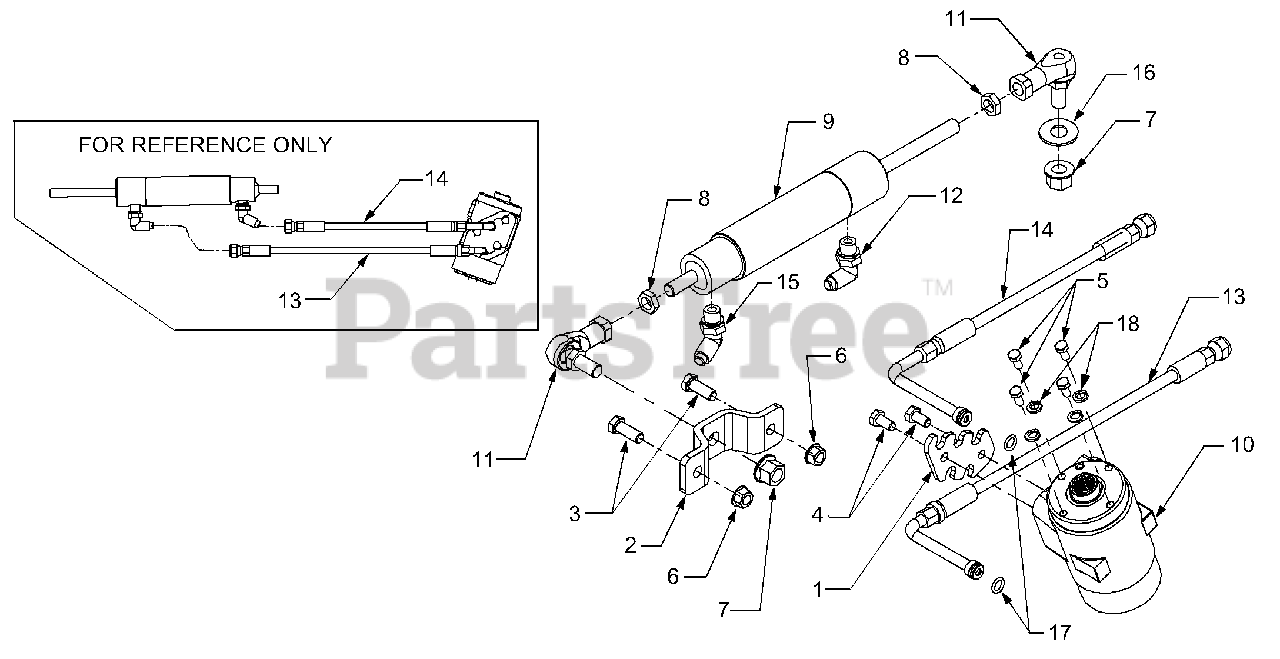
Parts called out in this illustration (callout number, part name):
1	Plate, Steering Pump Port
2	Bracket, Cylinder Mounting
3	Screw, Hex Cap 3/8-16 x 1.0 GR5
4	Screw, Hex Cap M8-1.25 x 16MM GR5
5	Screw, Hex Cap, M6 x 14MM
6	Nut, Hex Flange Lock, 3/8-16
7	Nut, Hex Flange Lock, M12 x 1.75
8	Nut, Hex, M12 x 1.75 RH
9	Cylinder, Steering
10	Pump, Hydraulic Steering
11	Ball Joint, 12MM x 1.75 RH
12	Fitting, 90 Degree Elbow
13	Hose, Front Steering
14	Hose, Rear Steering
15	Fitting, 45 Degree
16	Washer, Flat, .51 x 1.12 x .060
17	O-Ring, .426 x .566 x .070
18	Washer, Lock, 1/4"
